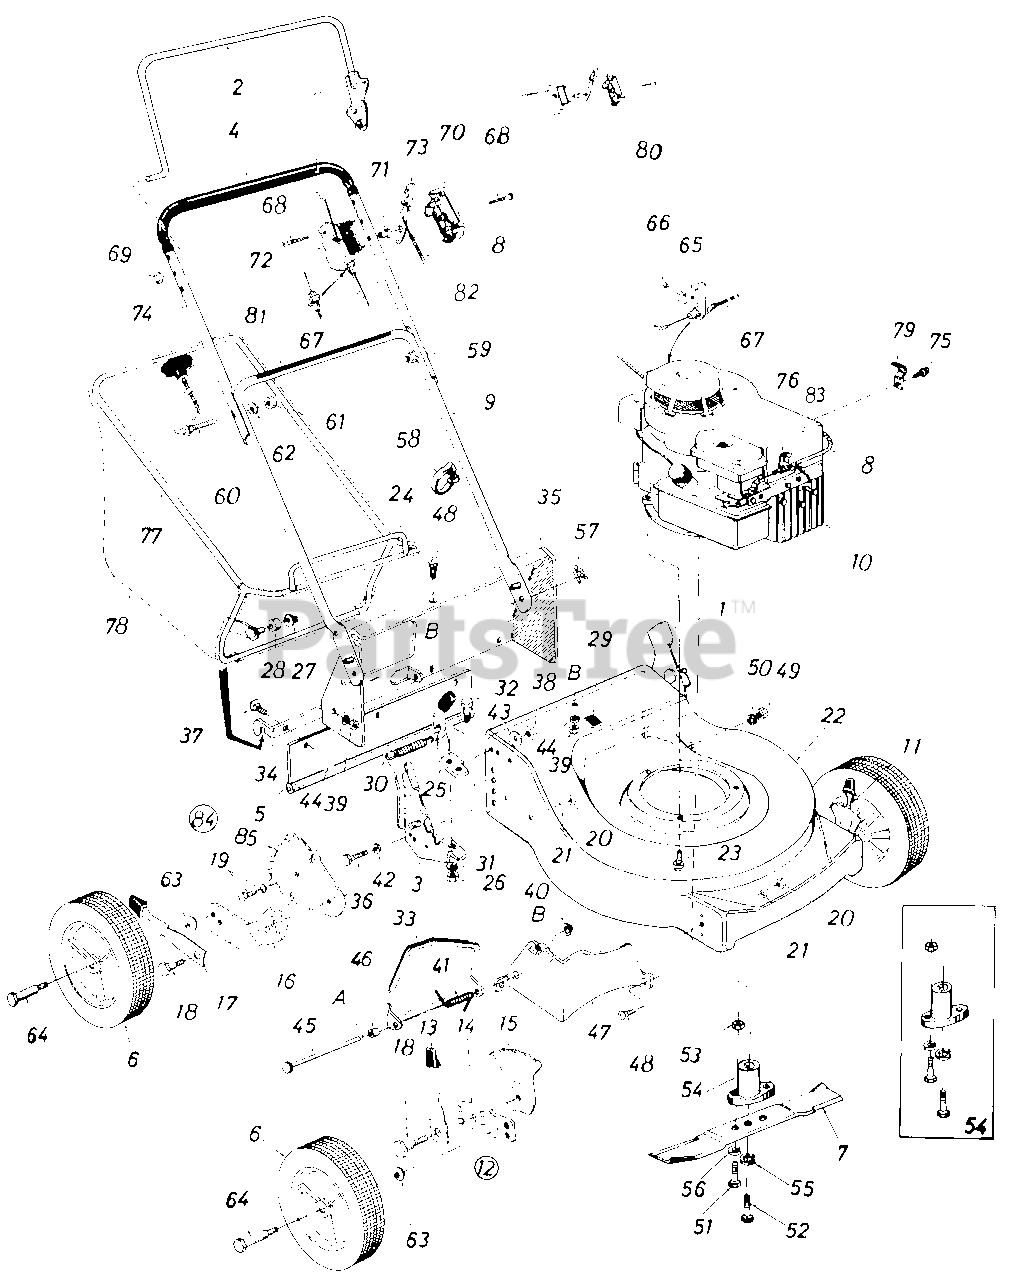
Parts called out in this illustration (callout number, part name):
1	Handle Brkt. Assy.-L.H.
2	Control Handle Ass'y.-L.H.
3	Handle Brkt. Ass'y.-R.H.
4	Grip
5	Rear Flap Ass'y.
6	Wheel Ass'y.
7	21" Blade
8	Throttle Wire-58" (Black)
9	Lower Handle (Chrome)
10	Engine
11	Front L.H. Height Adj. Ass'y.
12	Front R.H. Height Adj. Ass'y.
13	Spring Lever Ass'y. wlKnob
14	Front Pivot Bar
15	Front Index Plate
16	Rear Pivot Bar-R.H.
17	Spring Lever w/Knob
18	Shld. Bolt .50" Dia. x .375
19	Hex Wash. Hd. Tap Scr. 1/4 x.62" Lg.
20	Hex Nut 3/8-16 Thd.
21	Bell-Wash. .39" I.D. x .38"
26	Hex Nut 5/16-18 Thd.
27	Push Nut 3/8" Rod
28	Plastic Roller
29	Plug-Catcher Hook Slot
30	Tension Spring
31	L-Wash. 5/16" I.D.
32	Shld. Bolt .437" Dia. x .162
33	Chute Door
34	Grass Catcher Hitch Brkt.
35	Rear Discharge Deck Section
36	Hex Bolt 1/4-28 x .75" Lg.
37	Carr. Bolt 1/4-20 x .75" Lg.
38	Hex Nut 1/4-28 Thd.
39	Sems Nut 1/4-20 Thd.
40	Push Nut 1/4" Rod
41	Torsion Spring
42	L-Wash. 1/4" I.D.
43	Bell-Wash. 1/4" I.D. x .88" O.D.
44	Fl-Wash. .285" I.D. x 1.25" O.D.
45	Hinge Pin .250" Dia. x 7.25"
46	Spacer.262" I.D. x .31" O.D. x .58
47	Rear Baffle
48	Carriage Bolt 1/4-20 x .50" Lg.*
49	Hex Nut 1/4-20 Thd.
50	L-Wash. 1/4" I.D.*
51	Hex Bolt 5/16-24 x 1.00" Lg. (Grade 5)
52	Hex Bolt 3/8-24 x 2.25" Lg. (Grade 5)
53	Hex Nut 5/16-24 Thd.
54	Blade Adapter Kit
55	L-Wash. 3/8" I.D.-H.D.
56	L-Wash. 5/16" I.D.
57	Intern. Cot. Pin 5/16" Dia.
58	Cable Tie
59	Curved Carriage Bolt 5/16-18 x 1.38" Lg.
60	Rope Guide Bolt
61	Hex Nut 5/16-18 Thd.
62	L-Wash. 5/16" I.D.
63	Bell-Wash. .400" I.D. x .88" O.D. x .060
64	Axle Bolt
65	Cable Bracket
66	Pop Rivet .156" Dia. x .379
67	Brake Control Cable-43.0"
68	Truss Mach. Hd. "B" Tap Scr. #12 x 1.50" Lg.
69	Cap Speed Nut 5/16" Rod
70	Control Panel Half
71	Control Disc Pin
72	Clutch Panel Half
73	Throttle Control Lever
74	Upper Handle (Chrome)
75	Hex "B" Tap Scr. #10 x .38"
76	Casing Clamp
77	Grass Catcher Upper Frame
78	Grass Bag (Without Flip Top)
79	Casing Clamp
80	Control Housing Comp.
81	Instruction Label-Handle
82	Control Label-Throttle
83	Hex Wash. Hd. AB-Tap Scr. #8 x 38" Lg.
84	Rear Height Adj. Ass'y.-R.H.
85	Rear Index Plate
